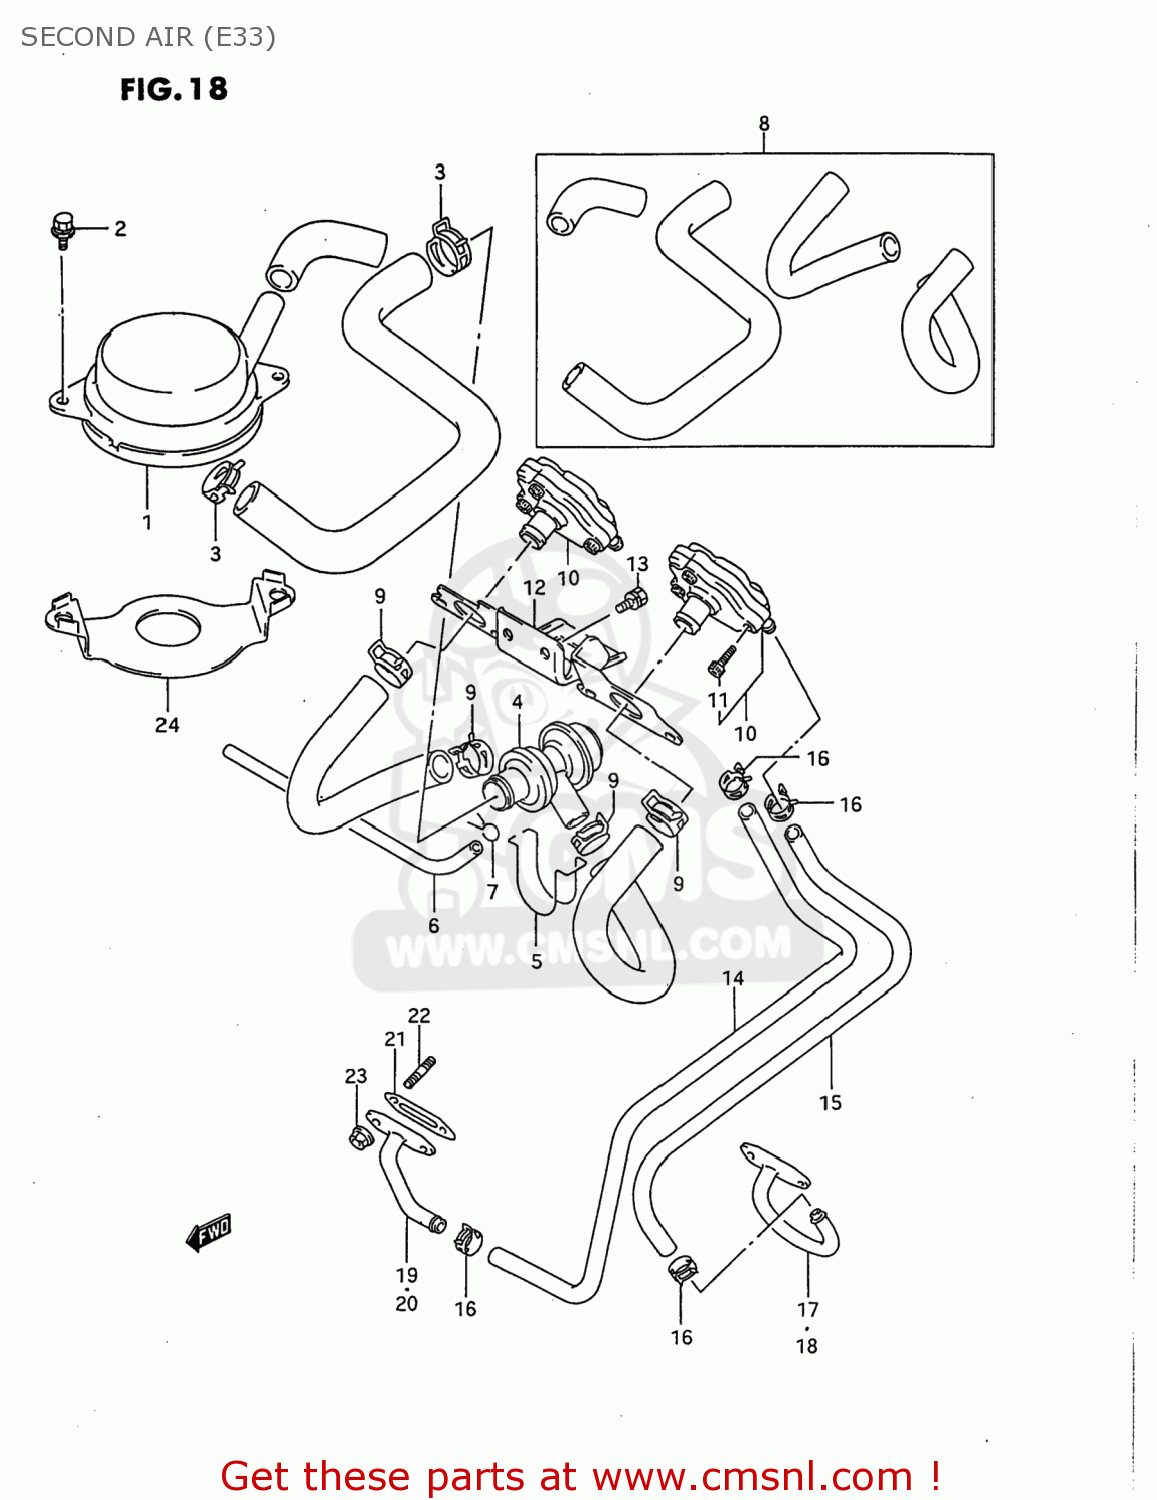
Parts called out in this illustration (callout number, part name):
1	CLEANER ASSEMBLY,SECOND AIR
2	BOLT
3	CLIP
4	VALVE ASSY,AIR SWITCHING
5	CLAMP,SWITCHING VALVE
6	HOSE(4.5X8.5X600)
7	CLAMP
8	HOSE SET,SECOND AIR NO.2
9	CLIP
10	VALVE ASSY,2ND AIR REED
11	BOLT
12	(CA) B/K REED VALVE
13	BOLT
14	HOSE,SECOND AIR NO.1,INLET
15	HOSE,SECOND AIR NO.1,INLET
16	CLIP
17	PIPE,2ND AIR NO.1
18	PIPE,2ND AIR NO.4
19	PIPE,SECOND AIR NO.2
20	PIPE,SECOND AIR NO.3
21	GASKET,SECOND AIR PIPE (NAS)
22	STUD BOLT
23	NUT
24	HOLDER,SECOND AIR CLEANER
